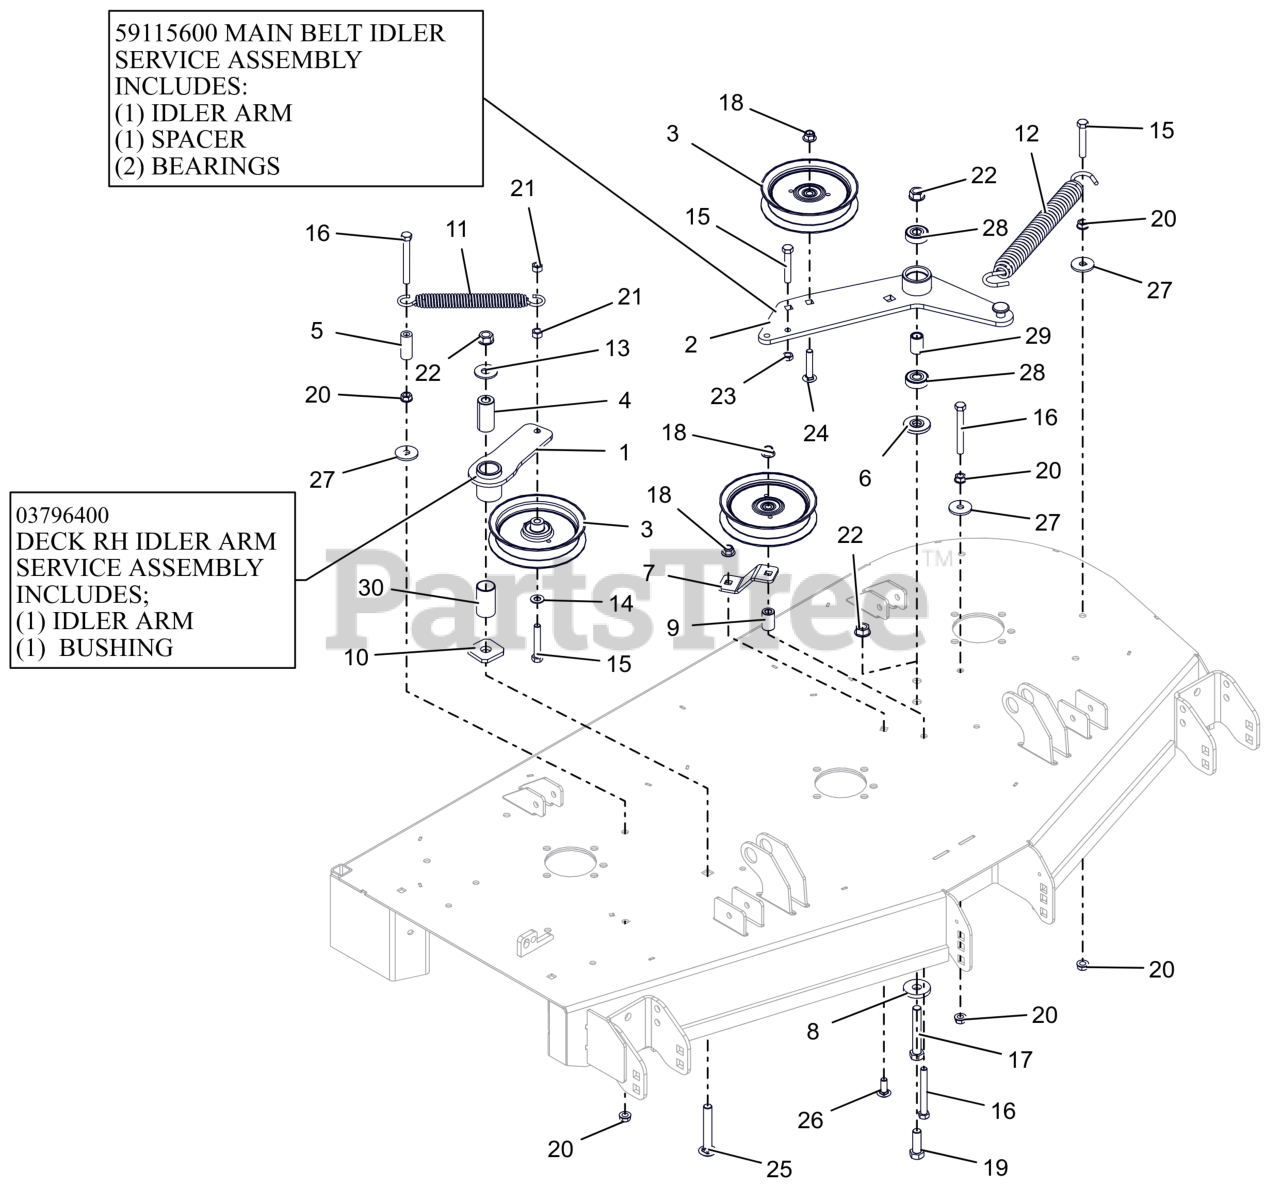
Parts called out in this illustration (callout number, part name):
1	WMT, IDLER ARM - BLACK
1	ASM, IDLER ARM (DECK)
2	WLDMT, DECK PTO IDLR ARM
2	ASSEMBLY, MAIN BELT IDLER
3	IDLER, FLAT 5.00"
4	BSHG, SPCR .502X.997X2.03 PM
5	HOSE, .38 X 1.65
6	SPACER, IDLER ARM
7	PTO FIXED IDLER MTG BRKT-ORG
8	WSHR-FL-STL 0.557X1.625X0.25 ZCC
9	BUSHING, SLV .380X.750X1.190
10	WSHR-FLT .640X1.75X.250
11	SPRING, EXTENSION
12	SPRING, EXTENSION
13	WSHR,FLT .563X1.375X.109 ZCC
14	WSHR,FLT .406X.812X.065 ZCC
15	BLT,HEX .38-16X2.25 G5 ZCC
16	BLT, HEX .38-16X3.25 G5 ZCC
17	BLT,HEX .50-13X3.25 G5 ZCC
18	NUT,NYL-FLG .38-16 GF ZCC
19	BLT,HEX .50-13X1.50 G5 ZCC
20	NUT, SPNLK-FLG .38-16 G5 ZCC
21	NUT-LK-CTR .38-16 ZC120
22	NUT-LK-CTR-FLG .500-13 GG ZCC
23	NUT-JAM .375-16 G2 ZCC
24	BLT,RHSSN.375-16X2.00 G5 ZCC
25	BTL,RHSSN .500-13 X 3.25 G5 ZCC
26	BLT,RHSSN .38-16X1.00 G5 ZCC
27	WSHR,FLT .406X1.375X.135 ZCC
28	BRG-BALL .500X1.38X.437
29	SPACER .510 X .75 X 1.1485
30	BSHG, 1.00X1.125X1.937
